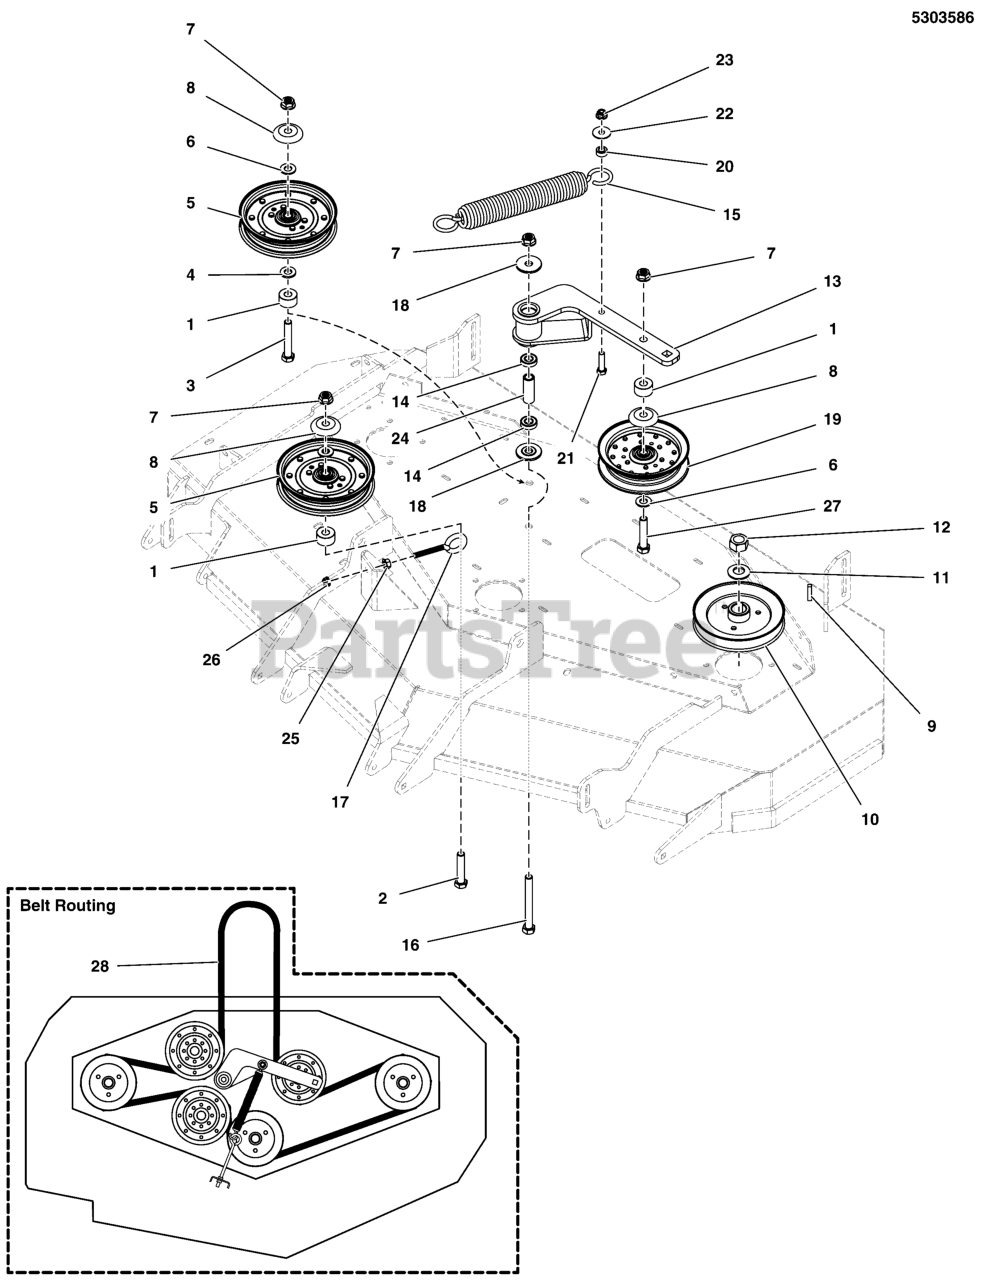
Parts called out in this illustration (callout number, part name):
1	SPACER, .52 X 1.25 X .70, PM, CZ
2	BOLT, 1/2-13 X 2-1/2" GD5 CZ
3	BOLT, 1/2-13 X 3" GD5 CZ
4	WASHER, 1/2" GD9 YZ
6	WASHER, 1/2 SAE
7	NUT, Hex Flange, Nylock, 1/2-13
8	SHIELD, PULLEY BEARING, CZ
9	KEY, 1/4" SQ. X 1-1/4
10	PULLEY, 5.926OB X .985ID, SINGLE B-SEC
11	WASHER, 3/4 BELLEVILLE CL/ZC
12	NUT, 3/4-16 Hex
13	WELD, TENSION ARM, 52" CUTTER DECK - BLK
14	BEARING, BALL, AXLE
15	SPRING, EXT, 1.5ODX12.25X.234WIRE BLK
16	BOLT, 1/2-13 X 4-1/2" GD5 YZ
17	EYEBOLT, 3/8-16 X 4, 2.13THRD, .75EYE, C
18	SPACER, IDLER ARM, 1/2, PM
20	SPACER, .39 X .75 X .38, PM, CZ
21	BOLT, 3/8-16 X 1-1/2" GD5 CZ
22	WASHER, 3/8" Fender
23	NUT, 3/8 - 16 HEX NYLOCK FLANGE
24	SPACER, .505 X .75 X 2.085, CZ
25	NUT, 3/8-16 Hex Large Serrated Flange
26	NUT, 5/16-18 HEX NYLOCK FLANGE NUT
27	BOLT, 1/2-13 X 2-1/2" GD5 CZ
28	BELT, 5V, 162.40"EL, ARAMID WRPD, RC
